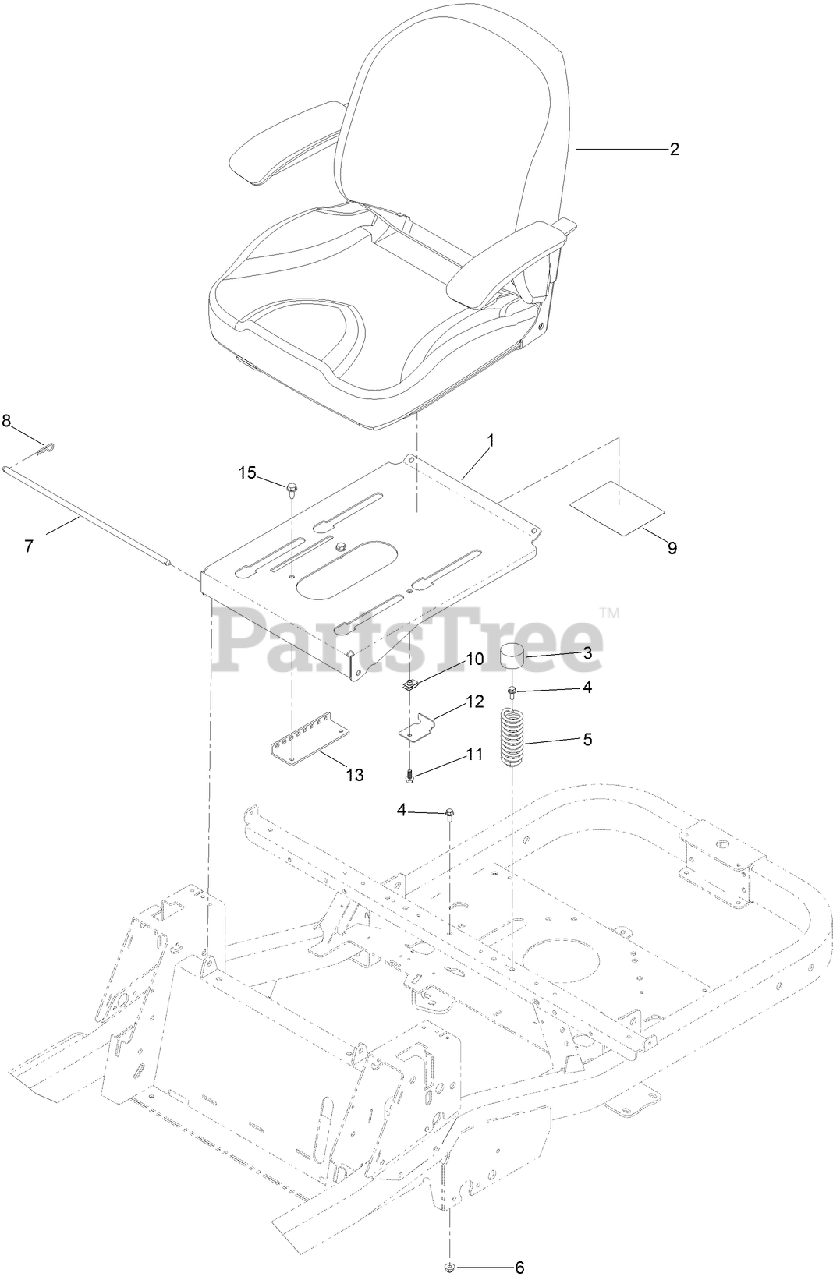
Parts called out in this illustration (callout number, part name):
1	PAN-SEAT
2	SEAT ASM
3	CAP-PROTECTOR
4	SCREW-HHF
5	SPRING-COMPRESSION
6	NUT-HF, NI
7	ROD-STOP
8	PIN-COTTER
9	DECAL-MAINTENANCE
11	SCREW-HHF
12	BRACKET-STOP, SEAT
13	BRACKET-LATCH, SEAT
15	SCREW-HWHTF
